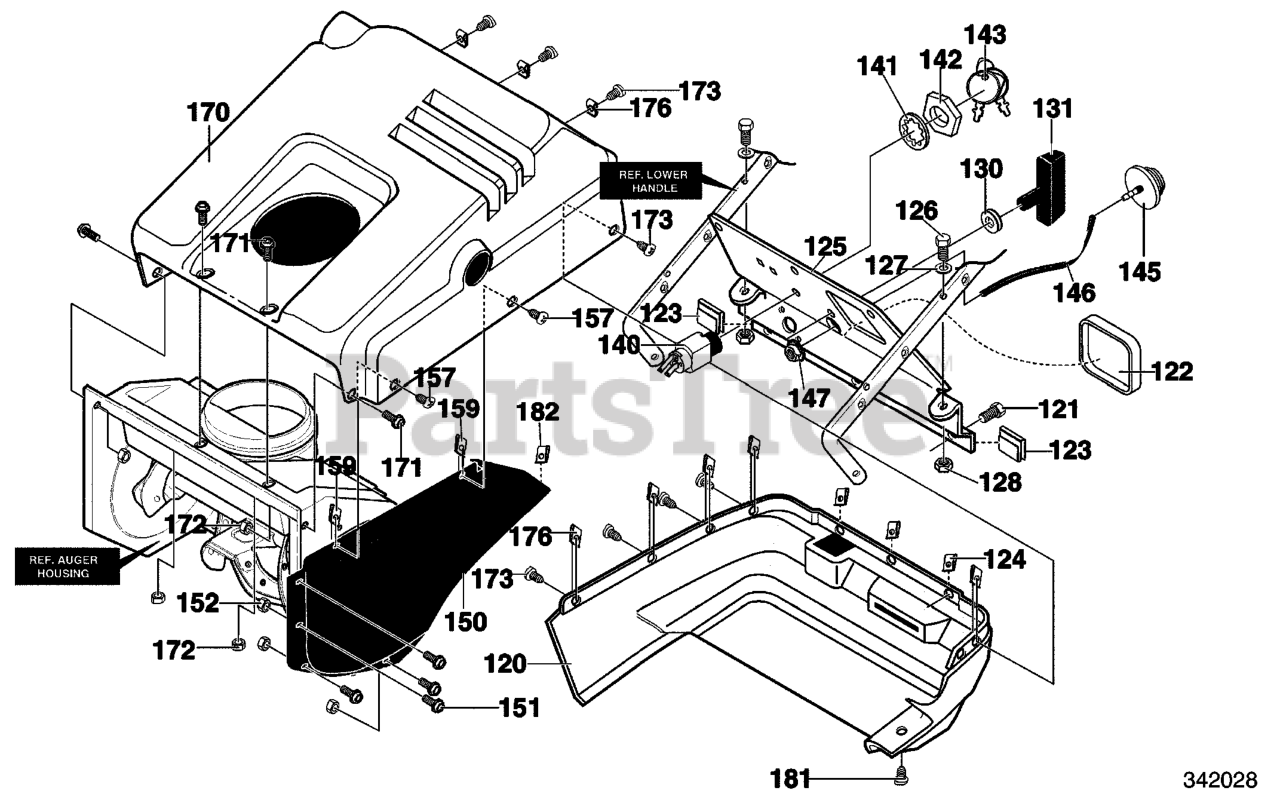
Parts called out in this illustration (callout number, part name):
120	COVER, BOTTOM
121	SCREW, 1/4-14X.75
122	PANEL, SPARK ACCESS
123	CLIP, "S" TINNERMAN
124	NUT, 1/4-10 SPEED J TYPE
125	CONTROL PANEL
126	SCREW, 1/4-20X1.25
127	FLATWASHER, .281X.63X.065
128	NUT, 1/4-20
130	GOMMET & WASHER
131	KNOB T
140	SWITCH, IGNITION
141	WASHER
142	NUT. 5/8-32
143	KEYS & RING
145	PRIMERBULB
146	HOSE PRIM 9.50LG
147	NUT, 1/4-20 REGHEXKEPS
150	COVER, BELT
151	SCREW, 10-24X.50
152	NUT, #10-24 REGHEXCTRLK
157	SCREW, 1/4-14X.75
159	NUT, 1/4-10 SPEED J TYPE
170	COVER, TOP
171	SCREW,#10-24X.50
172	NUT #10-24 REGHEXCTRLK
173	SCREW, 1/4-14X.75
176	NUT, 1/4-10 SPEED J TYPE
181	SCREW, 1/4-14X.75
182	NUT 1/4-10 SPEED J TYPE
